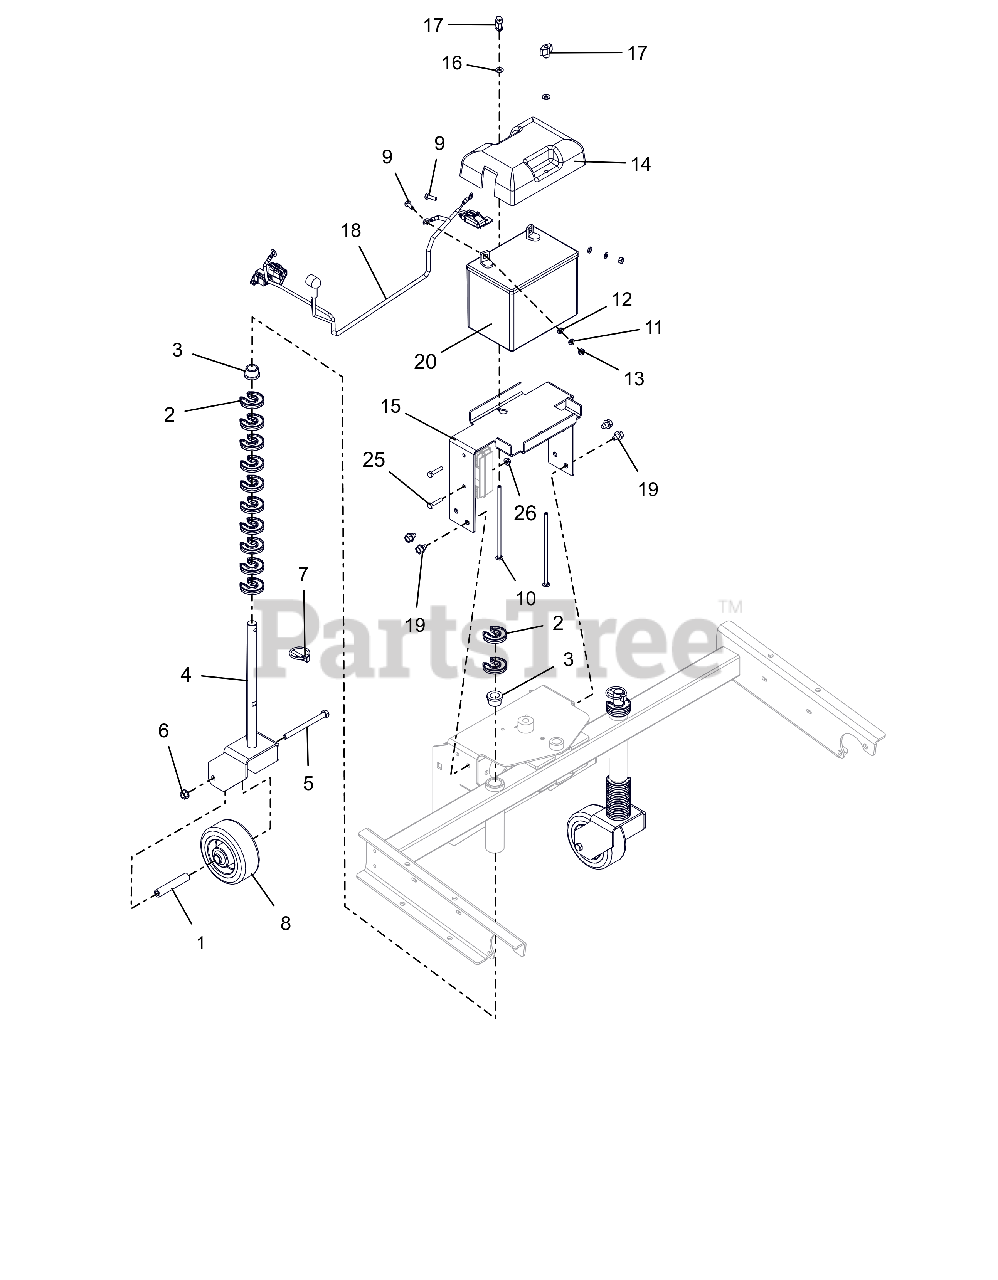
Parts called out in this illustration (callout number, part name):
1	SPACER, CASTER WHEEL
2	CLIP-HOC FIXED
3	BUSHING, FLANGE .75X.75X1.0
4	FORK, CASTER
5	BLT, HEX 0.375-16X4.5 GR5 ZCC
6	NUT-LK-TOP-FLG .38-16 ZC120
7	PIN, 1/4X1-9/16 LYNCH
8	WHEEL, CASTER - 5"OD
9	BLT, HEX .25-20X.75 G5 ZCC
10	BLT,RHSN .25-20X7.00 G2 ZCC
11	WSHR,LK-REG .250X.062 ZCC
12	WSHR,FLT .265X.500X.087 ZCC
13	NUT-STD .250-20 G2 ZCC
14	COVER, BATTERY
15	TRAY, BATTERY - POWER BRUSH
16	WSHR,FLT .281X.625X.065 ZCC
17	KNOB, WING - .25-20 UNC
18	HARNESS, ELECTRIC 12V BRUSH
19	SCR,TAP .375-16X.50 HWH TR ZCC
20	BATTERY, 300 CCA 10U1L
25	BLT, HEX .25-20X1.25 G5 ZCC
26	NUT-LK-TOP-FLG .250-20 GF ZCC
